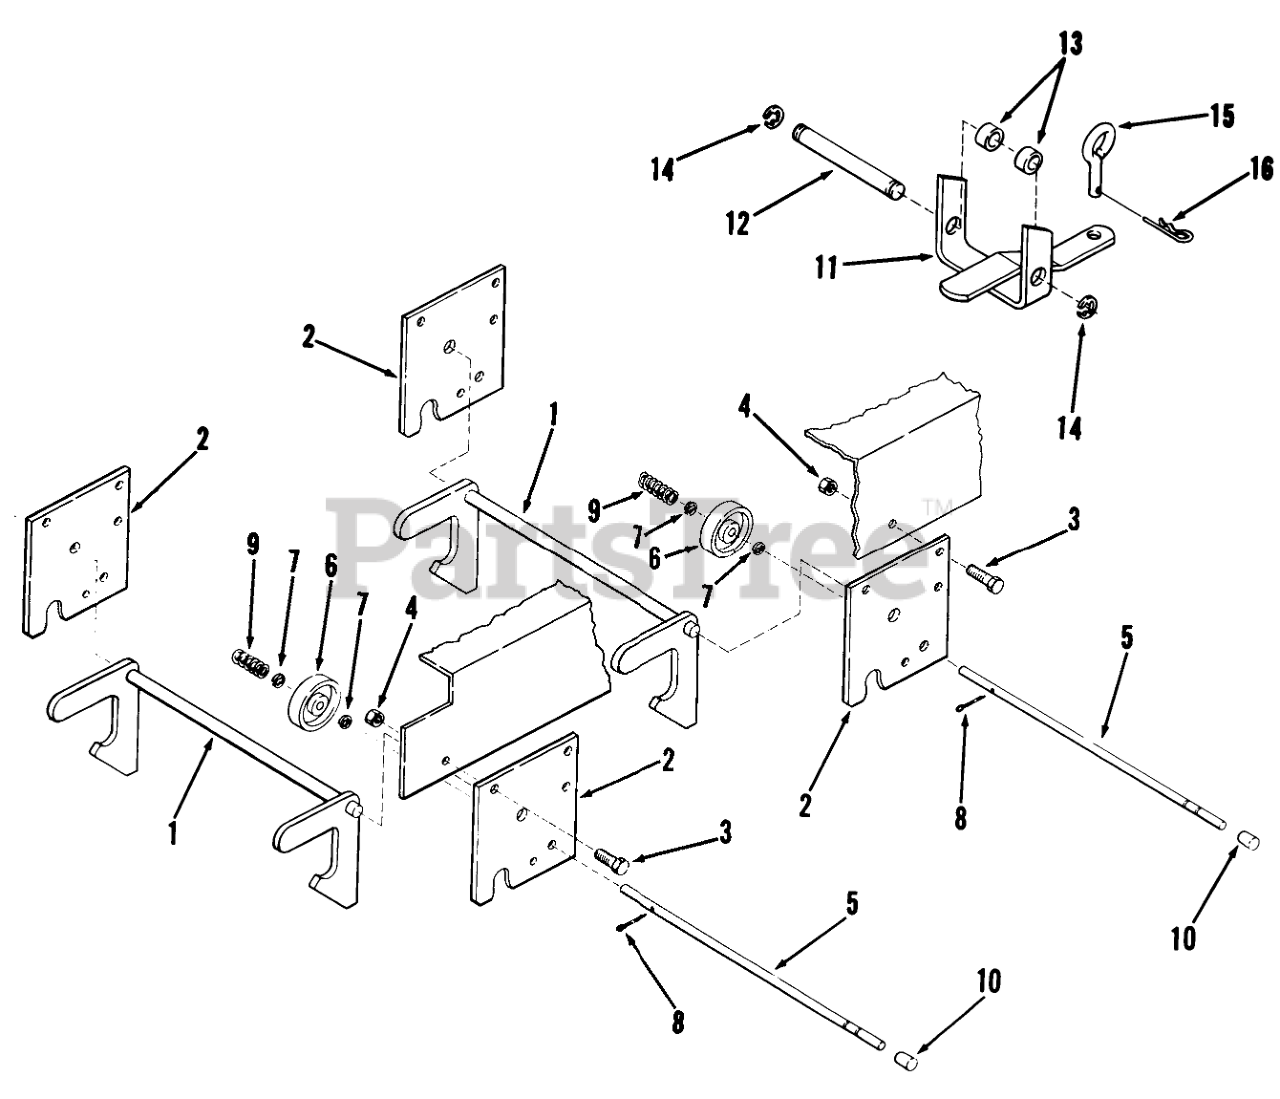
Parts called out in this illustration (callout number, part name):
1	Assy-Latch
2	Hitch Plate
3	BOLT
4	NUT
5	Rod Lock
7	RING-RETAINING
8	Cotter Pin
9	SPRING-COMPRESSION
10	CAP-ROD, PLUNGER
11	Hitch
12	PIN-STATIONARY HITCH
13	SPACER
14	E-RING
15	Pin-Tool
16	Hairpin Cotter
